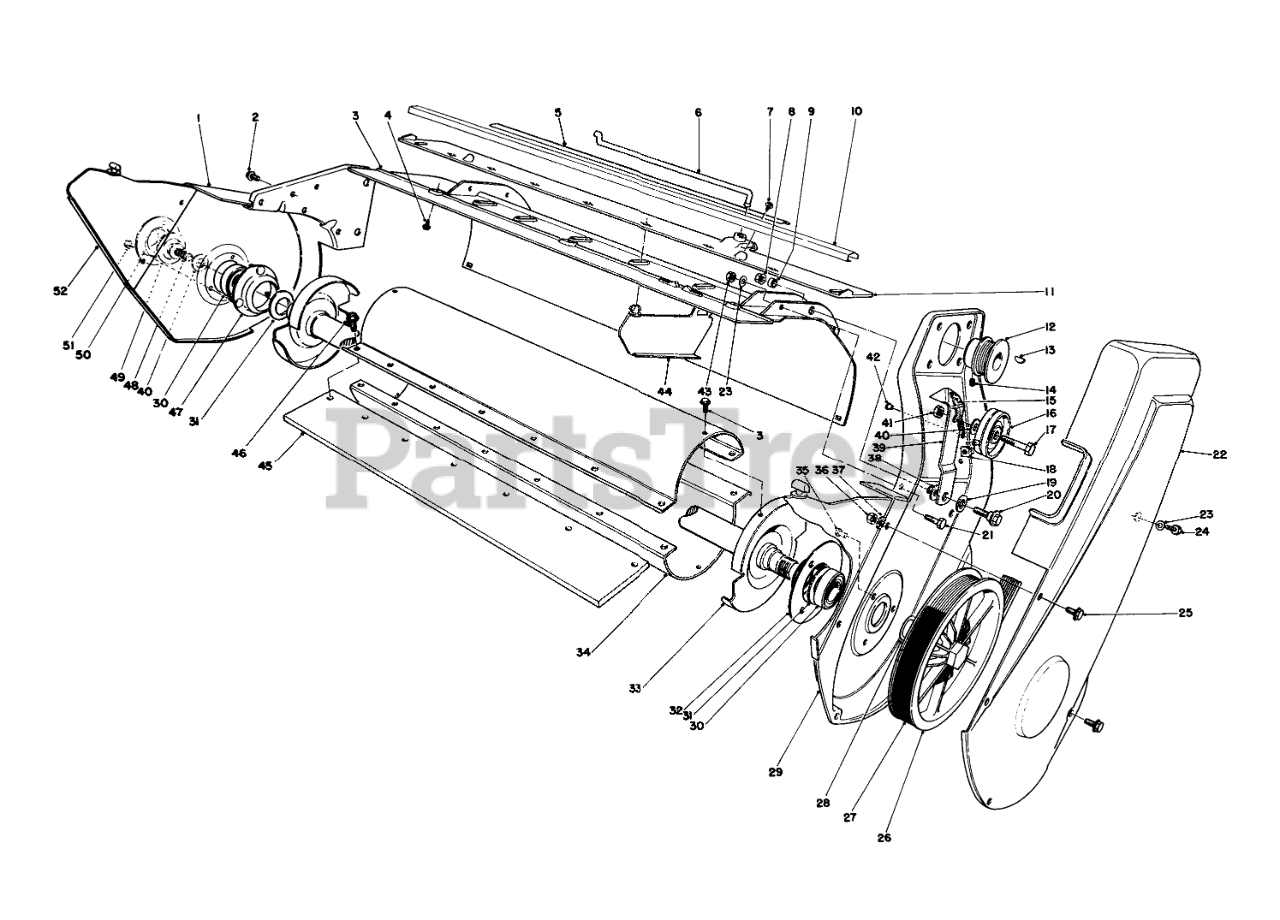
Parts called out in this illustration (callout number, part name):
1	Plate-R.H. Side
2	SCREW-HWH
3	HOUSING ASSEMBLY
4	SCREW-HWHTF
5	Decal-Warning
6	VANE ADJ LINKAGE
7	10-16 X 3/8 THDG SCREW
8	NUT-HF
9	SPACER
10	Moulding
11	Mount-Vane
12	Pulley
13	KEY-WOODRUFF
14	1/4-20X1/4 HEX SOC SS
15	IDLER SPRING
16	IDLER PULLEY
17	SCREW-HH
18	TINNERMAN NUT
19	WASHER
20	SCREW-SHOULDER
21	SCREW-HH
22	Drive Cover
23	WASHER-FLAT
24	SCREW-HEX HD
25	SCREW-SHWH
26	PULLEY ASM ROTOR
27	BELT - DRIVE
28	WASHER
29	Plate-L.H. Side
30	BEARING-BALL
31	WASHER-THRUST
32	FLANGE-BEARING
33	END CAP WA
34	ROTOR SHELL
35	RIVET
36	NUT-LOCK, NI
37	WASHER-FLAT
38	WASHER-PIVOT
39	IDLER ARM
40	WASHER-FLAT
41	NUT-LOCK, NI
42	Eyelet
43	NUT-LOCK, CONE
44	CENTER VANE
45	ROTOR BLADE
46	Screw
47	FLANGE-BEARING
48	SCREW-HHF
49	WASHER-RUBBER
50	Trough
51	NUT-CAP
52	OUTSIDE VANE
